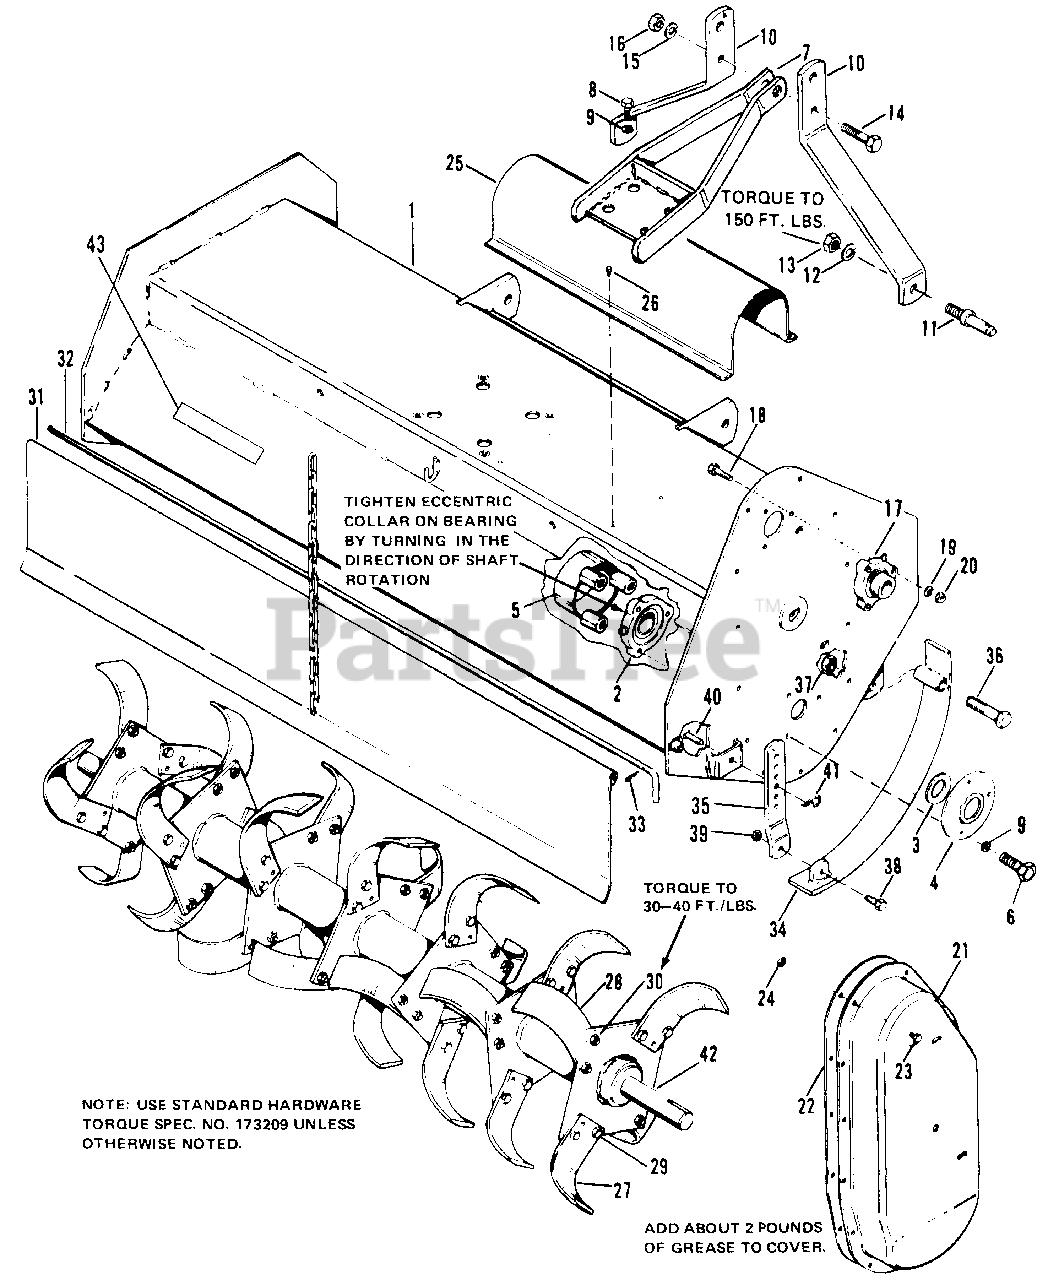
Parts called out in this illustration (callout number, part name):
1	FRAME ASSY, Main
2	BEARING, Flange
4	SEAL, Retaining
5	GUARD ASSY, Trash
6	CAPSCREW, Hex Hd., 3/8-16 x 1-3/4, Gr. 8
7	BRACE ASSY
8	CAPSCREW, Hex Hd., 3/8-16 x 1
9	LOCKWASHER, Spring, 3/8
11	PIN, Hitch
12	LOCKWASHER, Spring, 5/8
13	NUT, Hex, Full, 5/8-11
14	CAPSCREW, Hex Hd., 7/16-20 x 2-1/2
15	LOCKWASHER, Spring, 1/2
16	NUT, Hex, Full, 1/2-20
17	BEARING, Flange
18	CAPSCREW, Hex Hd., 5/16-18 x 1-1/2
19	LOCKWASHER, Spring, 5/16
20	NUT, Hex, 5/16-18
21	COVER ASSY
23	CAPSCREW, Hex Hd., 5/16-18 x 5/8
24	NUT, Hex, Lock, 5/16-18
26	SCREW, Hex, Wshr. Hd, Taptite, 1/4-20 x 3/8
27	TINE BLADE, R.H.
28	TINE BLADE, L.H.
29	CAPSCREW, Hex Hd., 3/8-16 x 1
30	NUT, Hex, Lock, 3/8-16
31	DEFLECTOR ASSY
32	ROD, Deflector
33	PIN, Cotter, 3/32 x 1
35	BRACKET, Adj.
36	CAPSCREW, Hex Hd., 5/8-11 x 3
37	NUT, Hex, Full Lock, 5/8-11
38	CAPSCREW, Hex Hd., 3/8-16 x 1
39	NUT, Hex, Full Lock, 3/8-16
40	PIN, Yoke, 3/8
41	PIN, Quick, 1 x 7/8
42	ROTOR ASSY
43	DECAL, Safety
